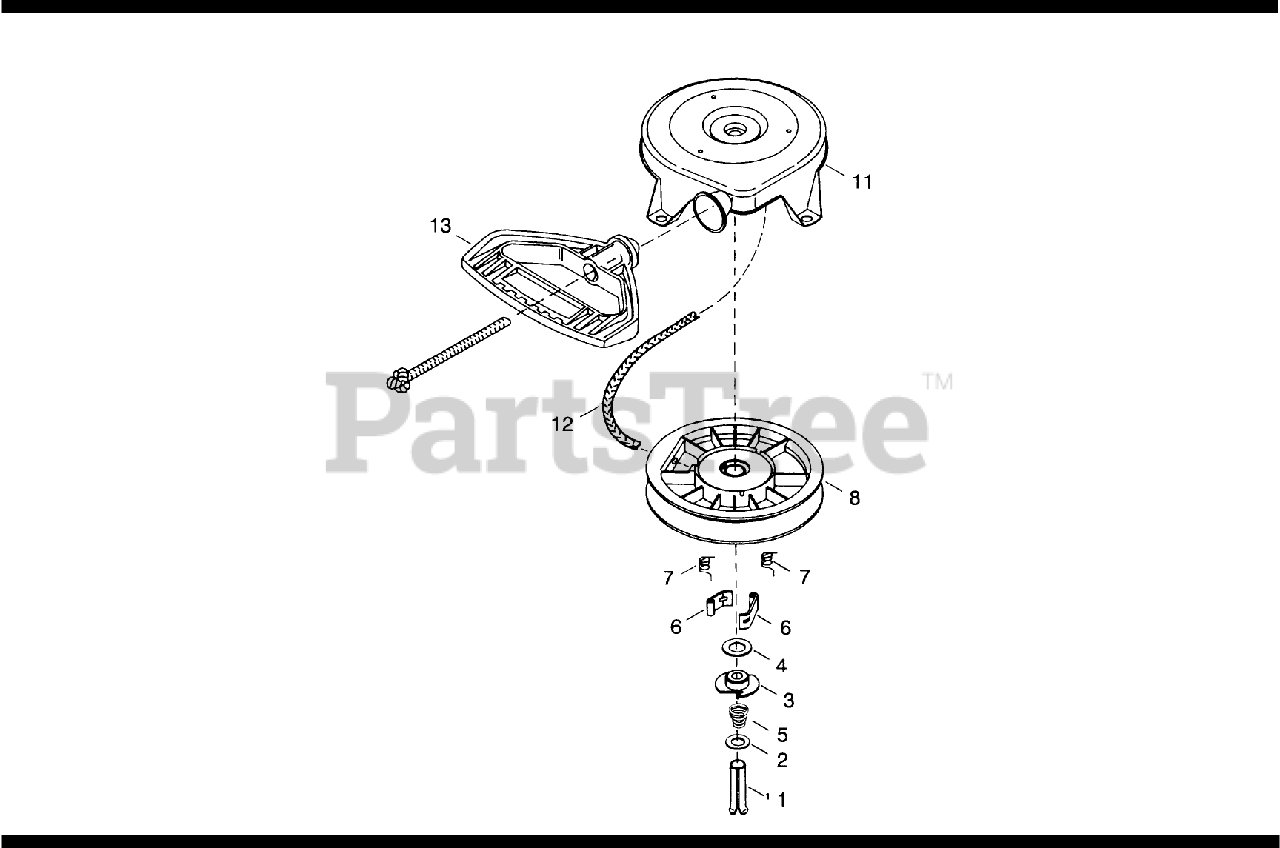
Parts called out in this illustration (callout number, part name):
1	Pin, Spring (Incl. Ref. #7)
2	Washer
3	Retainer
4	Washer
5	Spring-Brake
6	Dog-Starter
7	Spring-Dog
8	Pulley and Rewind Spring ASM
11	Housing Assy.-Starter
12	Rope-Starter
13	Handle-Starter, Mitten Grip
